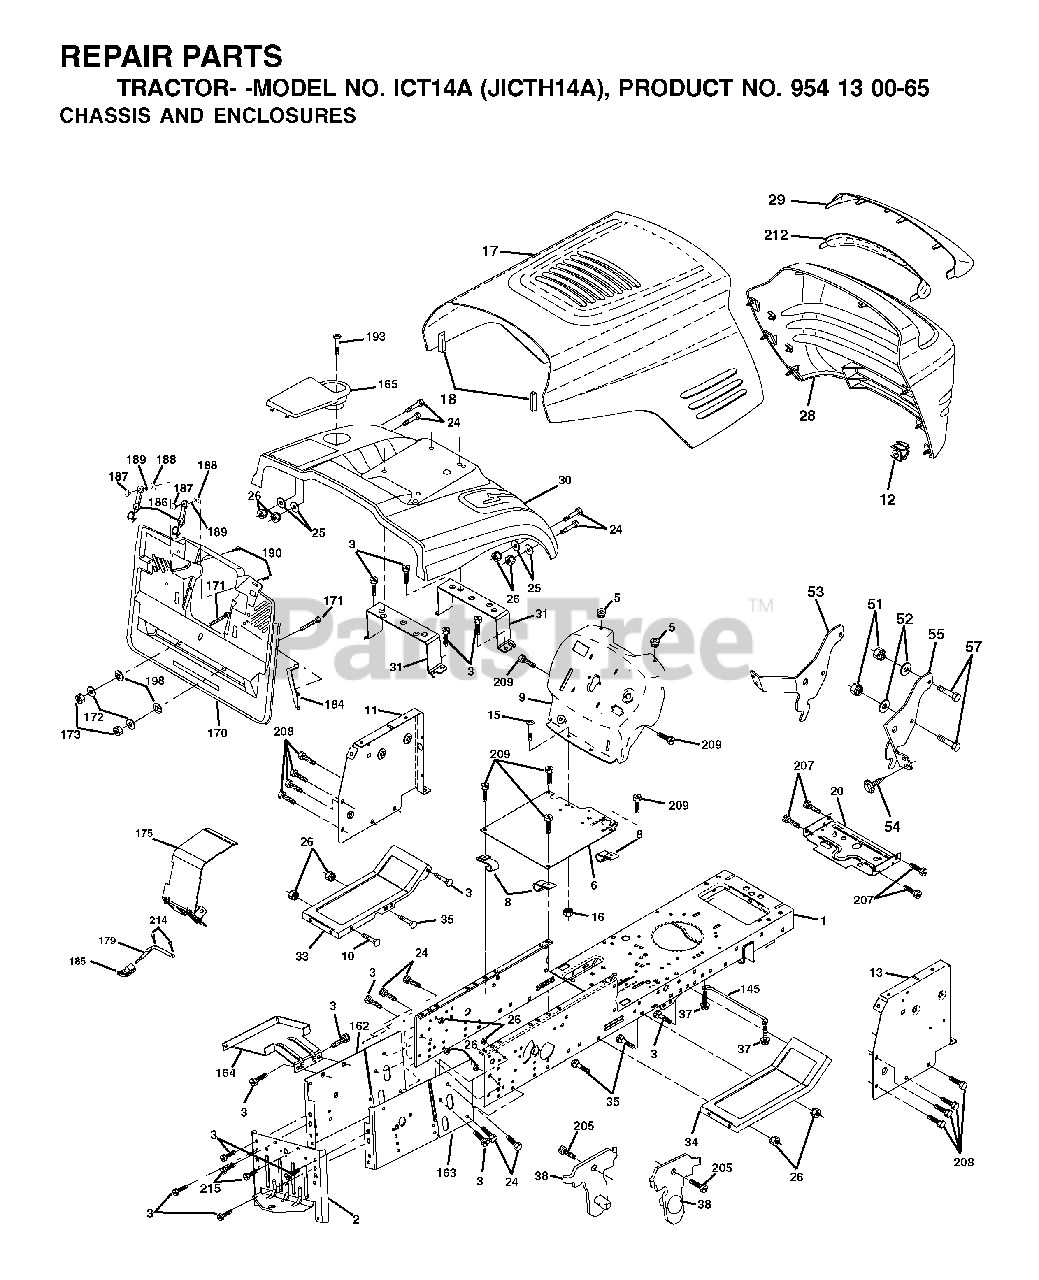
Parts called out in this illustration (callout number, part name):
1	CHASSIS
3	SCREW 3/8-16X3/4
5	BUMPER.RUBBER.HOOD
6	SADDLE FLAT
8	CLIP,INSULATOR
10	BOLT D
11	PANEL DASH LH
13	DASH PANEL RH
16	NUT
18	BUMPER HOOD T
20	PLATE MTG.BATTERY/FUEL TANK
25	WASHER
26	NUT
31	BRACKET SUPPORT FENDER
38	BRACKET.ASM.PIVOT.MOWER.REAR
51	LOCKNUT
57	BOLT
145	ROD PIVOT CHASSIS/HOOD
164	SUPPORT
171	BOLT
172	WASHER
186	LATCH ASSY
187	WELDNUT
189	LOCKWASHER
193	SCREW, TRUSS 1/4-20 X 3/4"
207	SCREW, 5/16-18 X 1/2
208	SCREW 3/8-16X1/2
209	SCREW, 3/8-16X3/4
214	RETAINER M
215	SCREW 5/16-18X1/2"
